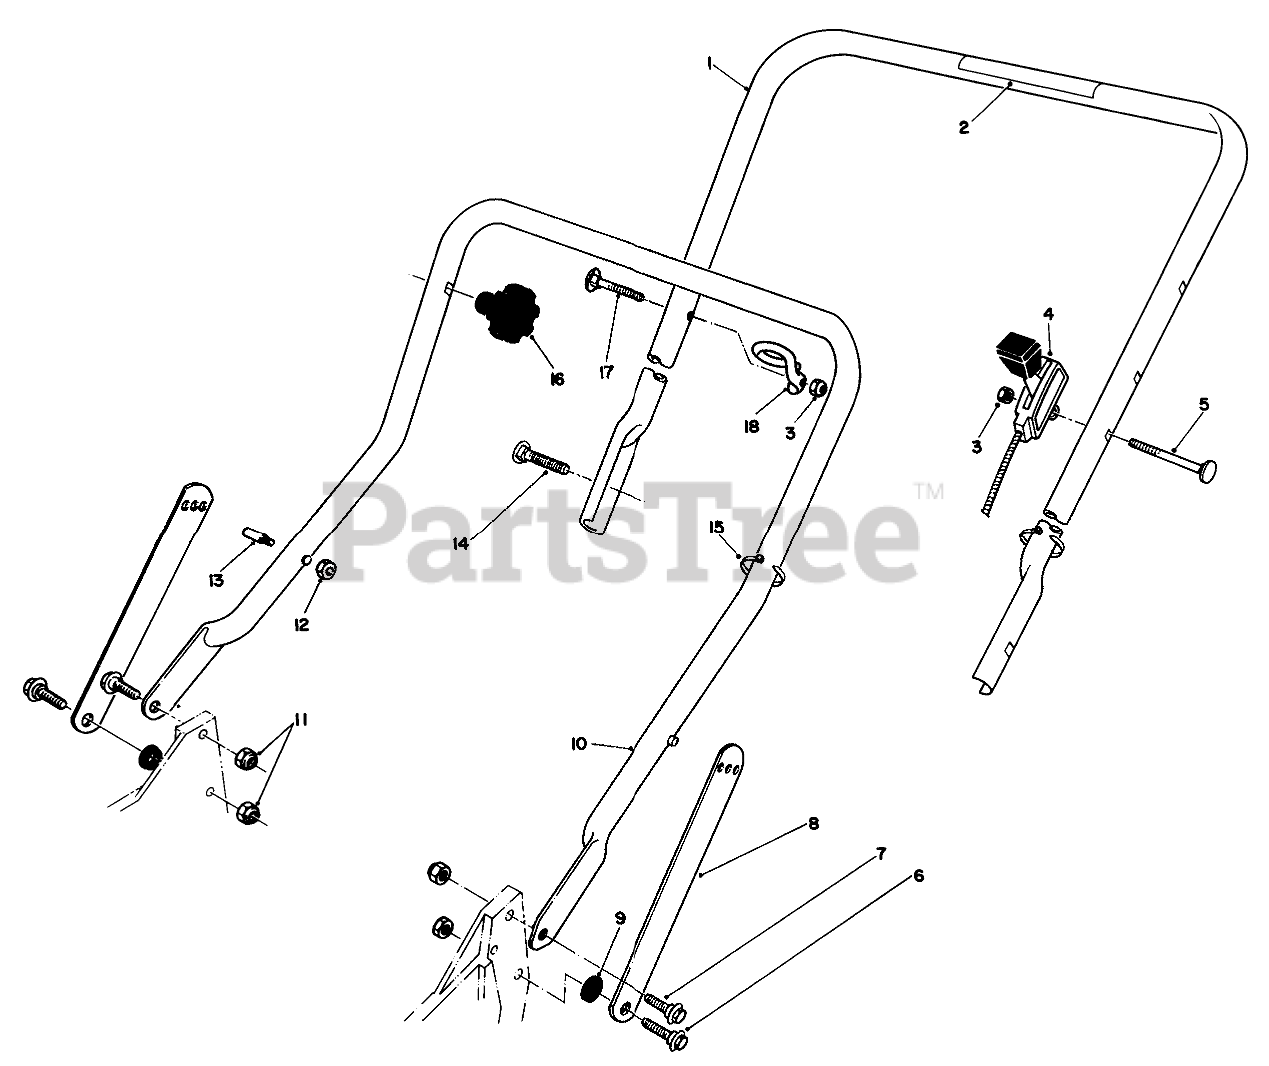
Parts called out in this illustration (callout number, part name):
1	HANDLE W/DECAL
2	DECAL - HANDLE
3	NUT-LOCK, NI
4	THROTTLE CONTROL
5	SCREW-HANDLE
6	SCREW-SHOULDER
7	SCREW-SHOULDER
8	Handle Latch
9	SPACER
10	LOWER HANDLE ASM
11	NUT-LOCK, NI
12	NUT-LOCK, NI
13	HANDLE PIN
14	5/16-18 X 2 HNDLE SCREW
15	TIE-CABLE
17	HANDLE SCREW
18	Guide
